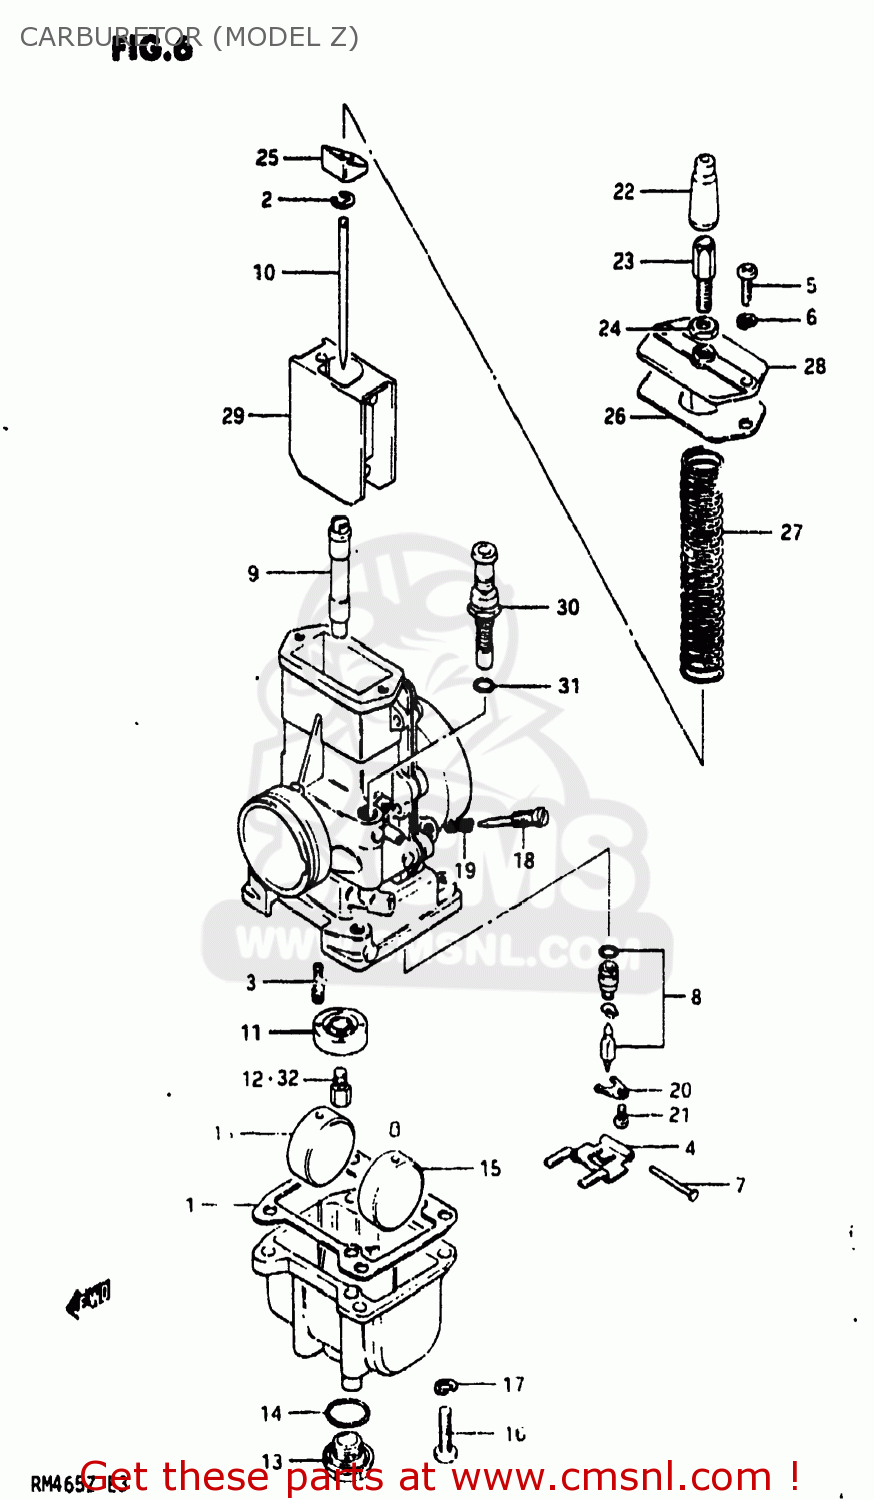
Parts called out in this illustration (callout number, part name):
1	GASKET,FLOAT CAHMBER (NAS)
2	CLIP
3	JET,PILOT(50)
4	ARM,FLOAT
5	SCREW
6	LOCK WASHER
7	PIN,FLOAT
8	VALVE ASSEMBLY,NEEDLE
9	JET,NEEDLE(R-0)
10	NEEDLE JET
11	RING,MAIN JET FIXING
12	JET
13	SCREW,GUIDE
14	O RING,DRAIN PLUG
15	FLOAT
16	SCREW 5X20
17	LOCK WASHER
18	SCREW,PILOT AIR
19	SPRING
20	PLATE
21	SCREW 4X6
22	CAP,CABLE ADJUSTER
23	ADJUSTER,CABLE
24	NUT
25	PLATE
26	SEAT,RETURN SPRING
27	GASKET,MIXING CHAMBER (NAS)
28	SPRING,THROTTLE VALVE
29	CAP,CARBURETOR,TOP
30	VALVE,THROTTLE
31	VALVE,STARTER
32	O-RING
33	JET
